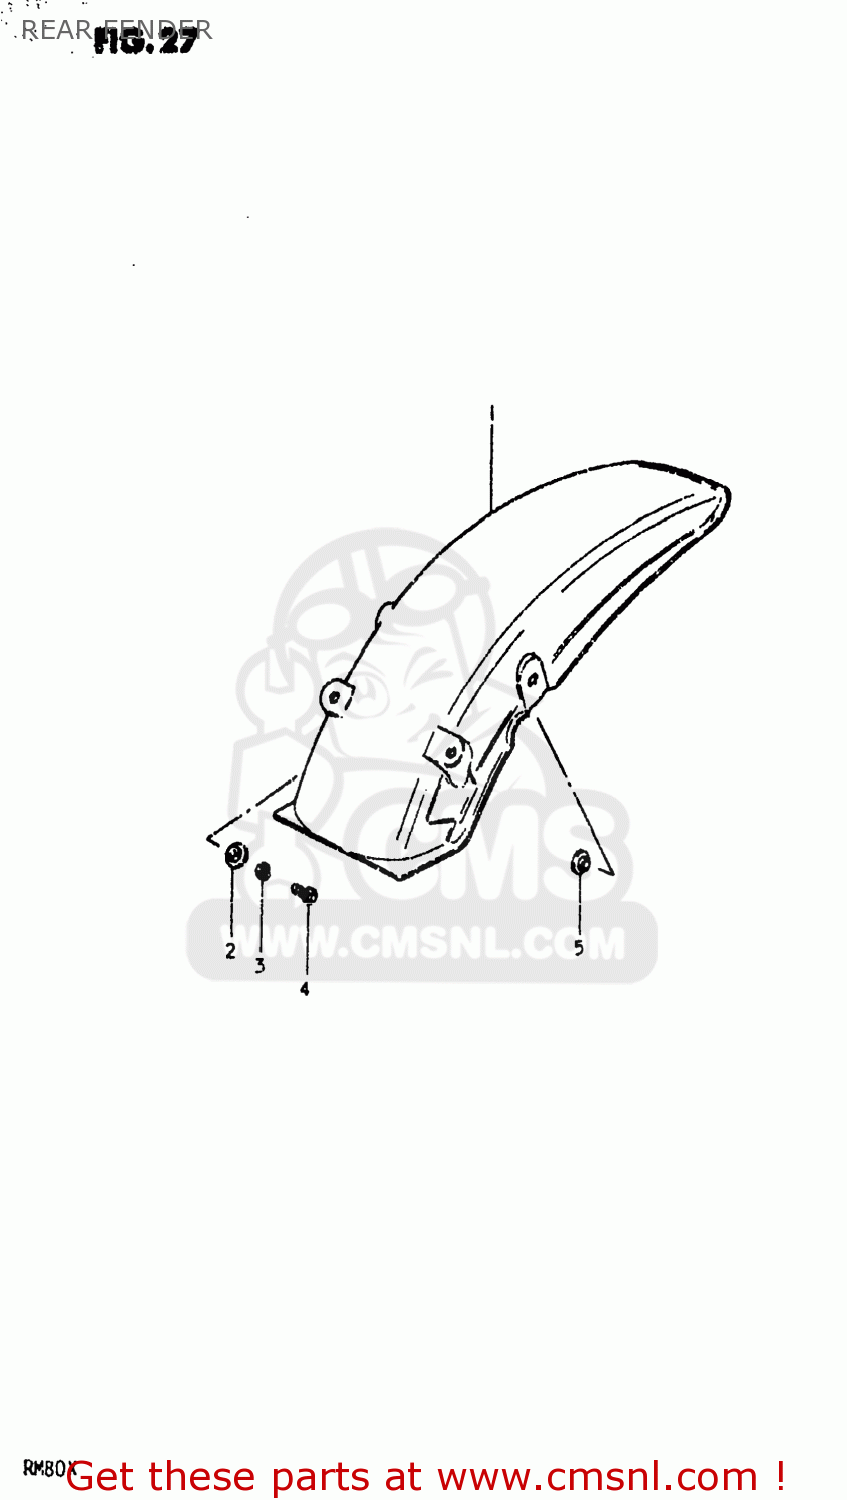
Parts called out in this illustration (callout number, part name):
1	FENDER,RR
2	WASHER
3	LOCK WASHER
4	BOLT, UPPER
5	WASHER
